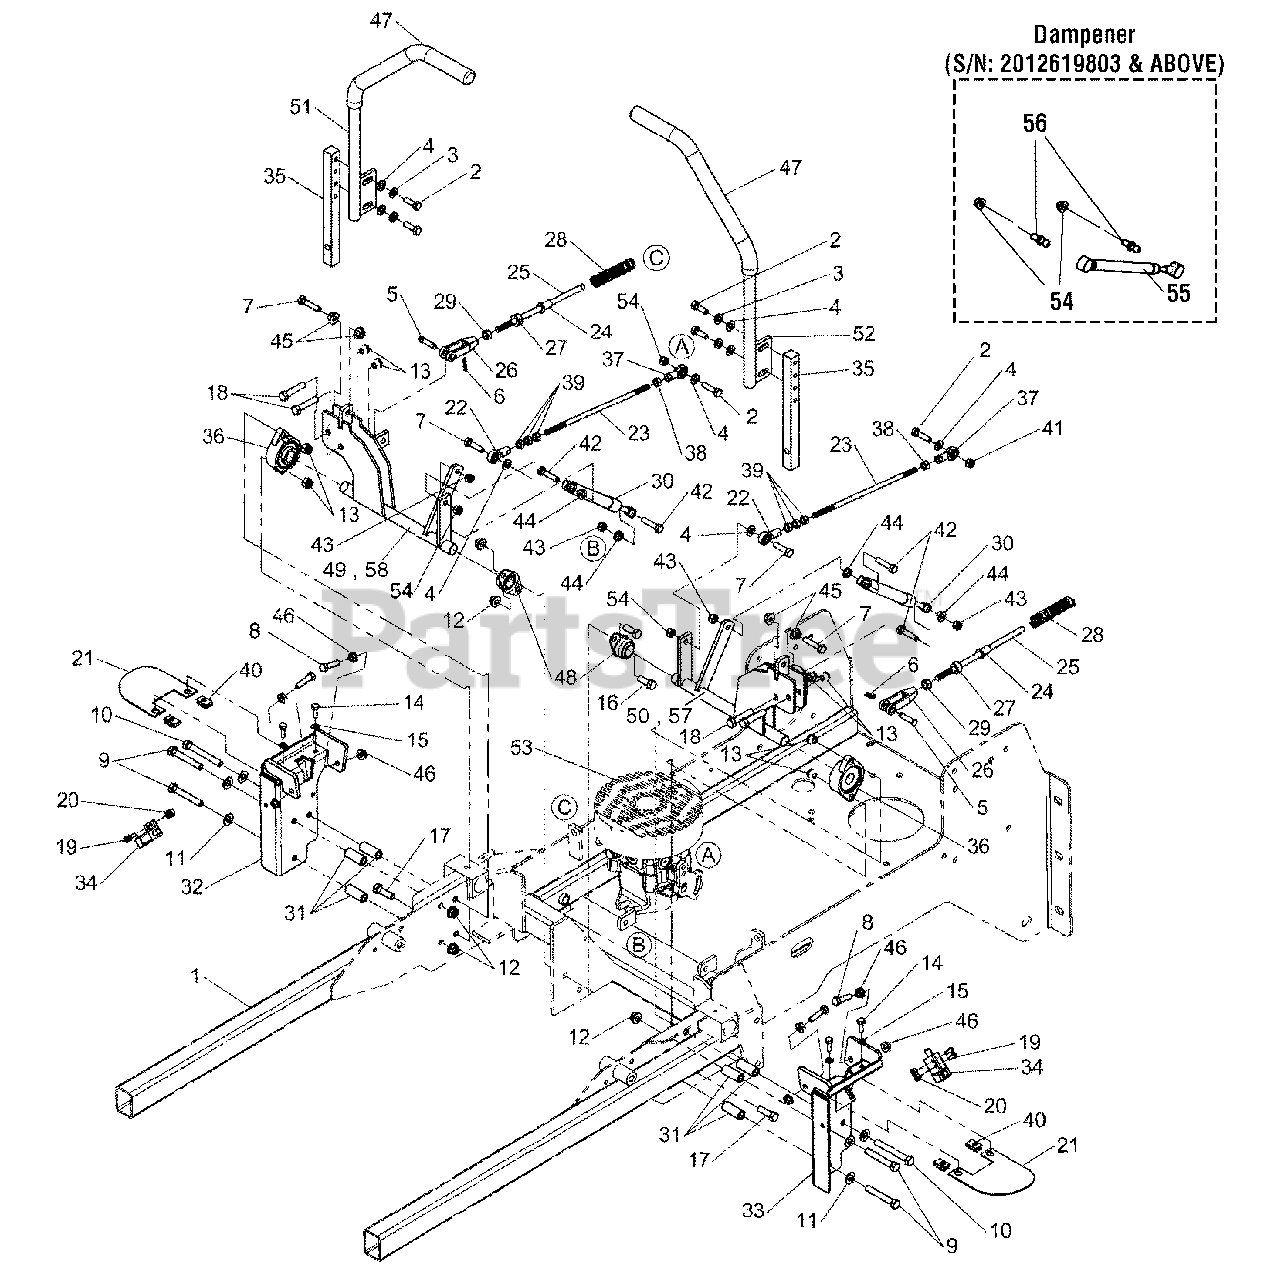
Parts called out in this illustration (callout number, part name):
1	MAIN FRAME
2	BOLT, 5/16-18 X 1"
3	WASHER, 5/16" Lock
4	WASHER, 5/16" SAE
5	PIN-CLEVIS, 5/16 X 1 YZ
6	HAIRPIN CLIP
7	BOLT, 5/16-18 X 1-1/4"
8	BOLT, 5/16-18 X 1-1/8"
9	BOLT, 3/8-16 X 2-1/2"
10	BOLT, 3/8-16 X 3"
11	WASHER, 3/8" SAE
12	NUT, 3/8-16 Hex Nylock Flange
13	NUT, 3/8-16 Hex Nylon Lock
14	BOLT, 1/4-20 X 3/4"
15	WASHER, 1/4 SAE (5025154)
16	BOLT, 3/8-16 X 1"
17	BOLT, 3/8-16 X 1-1/4"
18	BOLT, 3/8-16 X 1-3/4"
19	SCREW, #10-24 X 1/2"
20	NUT, #10-24 Hex
21	MOTION CONTROL GUARD
22	BALL JOINT 5/16-24 RH FEMALE STAMPED STL
23	HYDRO CONTROL ROD
24	BUSHING, Flange
25	NEUTRAL CONTROL ROD
26	CLEVIS, 3/8-24, Plastic
27	COLLAR, 3/8" Set
28	SPRING, Compression
29	NUT, 3/8-24 Hex
30	DAMPENER
31	SPACER, .39 X .63 X 1.50
32	NEUTRAL LOCK PLATE, RH
33	NEUTRAL LOCK PLATE, LH
34	SWITCH, PLUNGER, N.O./N.C.
35	MOUNT, CONTROL ARM - BLK
36	BEARING, Flange
37	BALL JOINT 5/16-24 LH FEMALE STAMPED STL
38	NUT, 5/16-24 Hex LH
39	NUT, 5/16-24 Hex
40	BODY CLIP, 1/4-20
41	NUT, 5/16-18 Hex Nylon Lock
42	BOLT, M8-1.25 x 35MM
43	NUT, M8-1.25 Hex Nylon Lock
44	NUT, M8-1.25 Hex Serrated Flange
45	NUT, 5/16-18 Hex Large Serrated Flange
46	NUT, 5/16-18 Hex Small Serrated Flange
48	BEARING, Flange
49	CONTROL SHAFT, RH
50	CONTROL SHAFT, LH
51	WELD, HANDLE MOTION CONTROL, RH - BLK
52	WELD, HANDLE MOTION CONTROL, LH - BLK
53	HYDRAULIC PUMP
54	NUT, 5/16" -18 NYLOCK FLANGE
55	DAMPENER, CONTROL, #(P6709/P3610)
56	BALL STUD, 5/16 X .50, (# PC-477-2)
57	WELD, CONTROL SHAFT, LH - ORG
58	WELD, CONTROL SHAFT, RH - ORG
